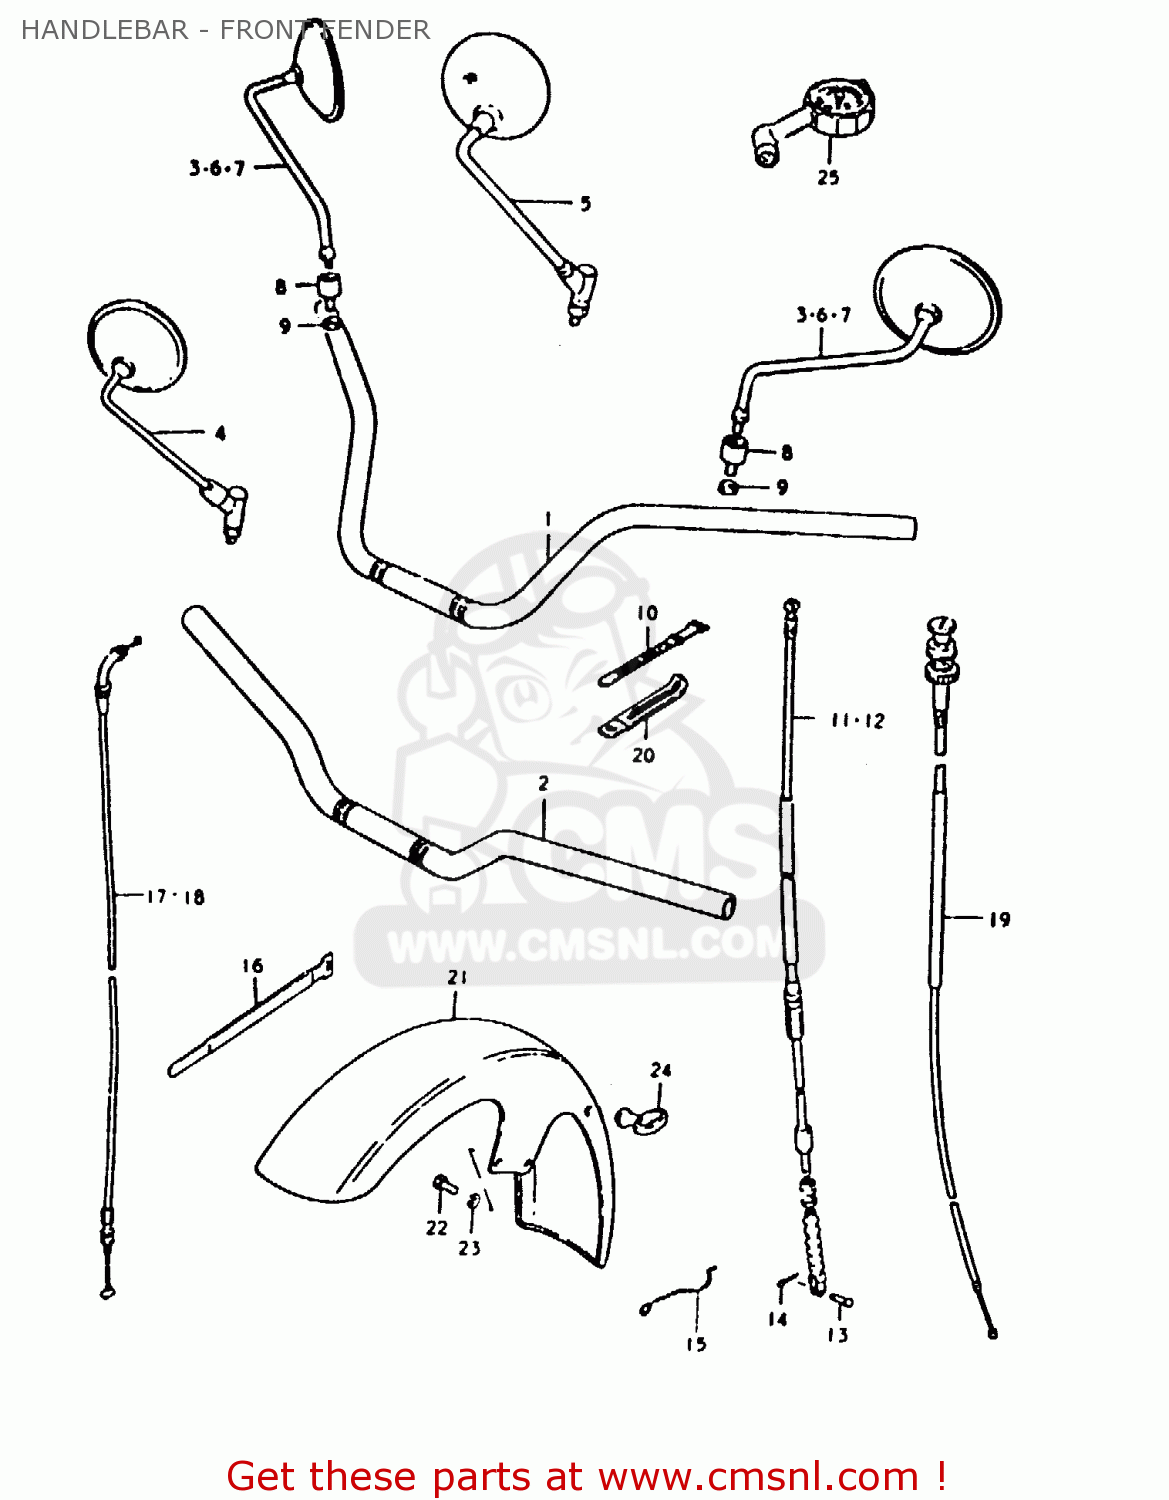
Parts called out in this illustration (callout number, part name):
1	HANDLEBAR
2	HANDLEBAR
4	MIRROR ASSY,RH
8	CUSHION,REAR VIEW MIRROR
9	NUT
10	CLAMP(L:120)
11	CABLE ASSY,CLUTCH
12	CABLE,CLUTCH
13	PIN(L:15)
14	PIN
15	GUIDE,CABLE
16	CLAMP
17	CABLE ASSEMBLY,THROTTLE
18	CABLE ASSEMBLY,THROTTLE
19	CABLE ASSEMBLY,STARTER
20	CLAMP
21	FENDER,FR
22	BOLT
23	LOCK WASHER
24	GUIDE,CABLE
25	GAUGE ASSY,AIR PRESSURE
